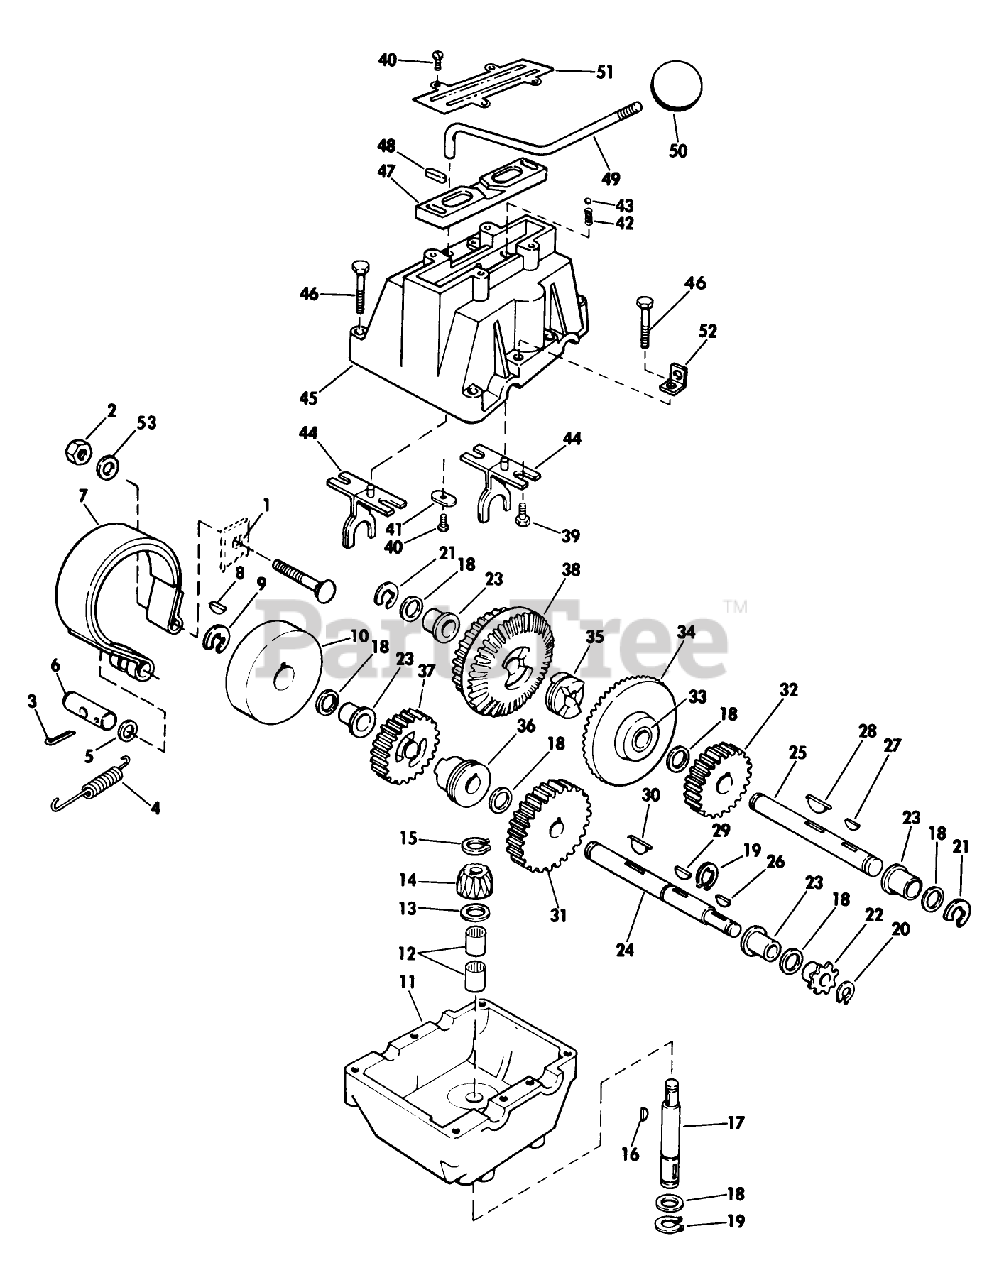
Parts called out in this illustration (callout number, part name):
11	Lower Housing
15	Retaining Ring
18	Washer (.040)
18	Washer (.030)
18	Washer (.050)
19	Retaining Ring
20	Retaining Ring
21	Retaining Ring
22	Sprocket-8 Tooth
24	Output Shaft
25	Drive Shaft
26	Key-Woodruff
27	Key-Woodruff
29	Key-Woodruft
31	Spur Gear-28 Tooth
32	Spur Gear-22 Tooth
34	Bevel Gear
37	Spur Gear-22 Tooth
38	Gear-Spur and Bevel
39	Screw Shoulder
41	Detent-Cover Plate
42	Spring-Detent
43	Ball-Detent
45	Housing-Upper
47	Cam Plate
48	Nylon Slide
49	Shift Lever
50	Shifter Knob
51	Top Cover Plate
52	Bracket
